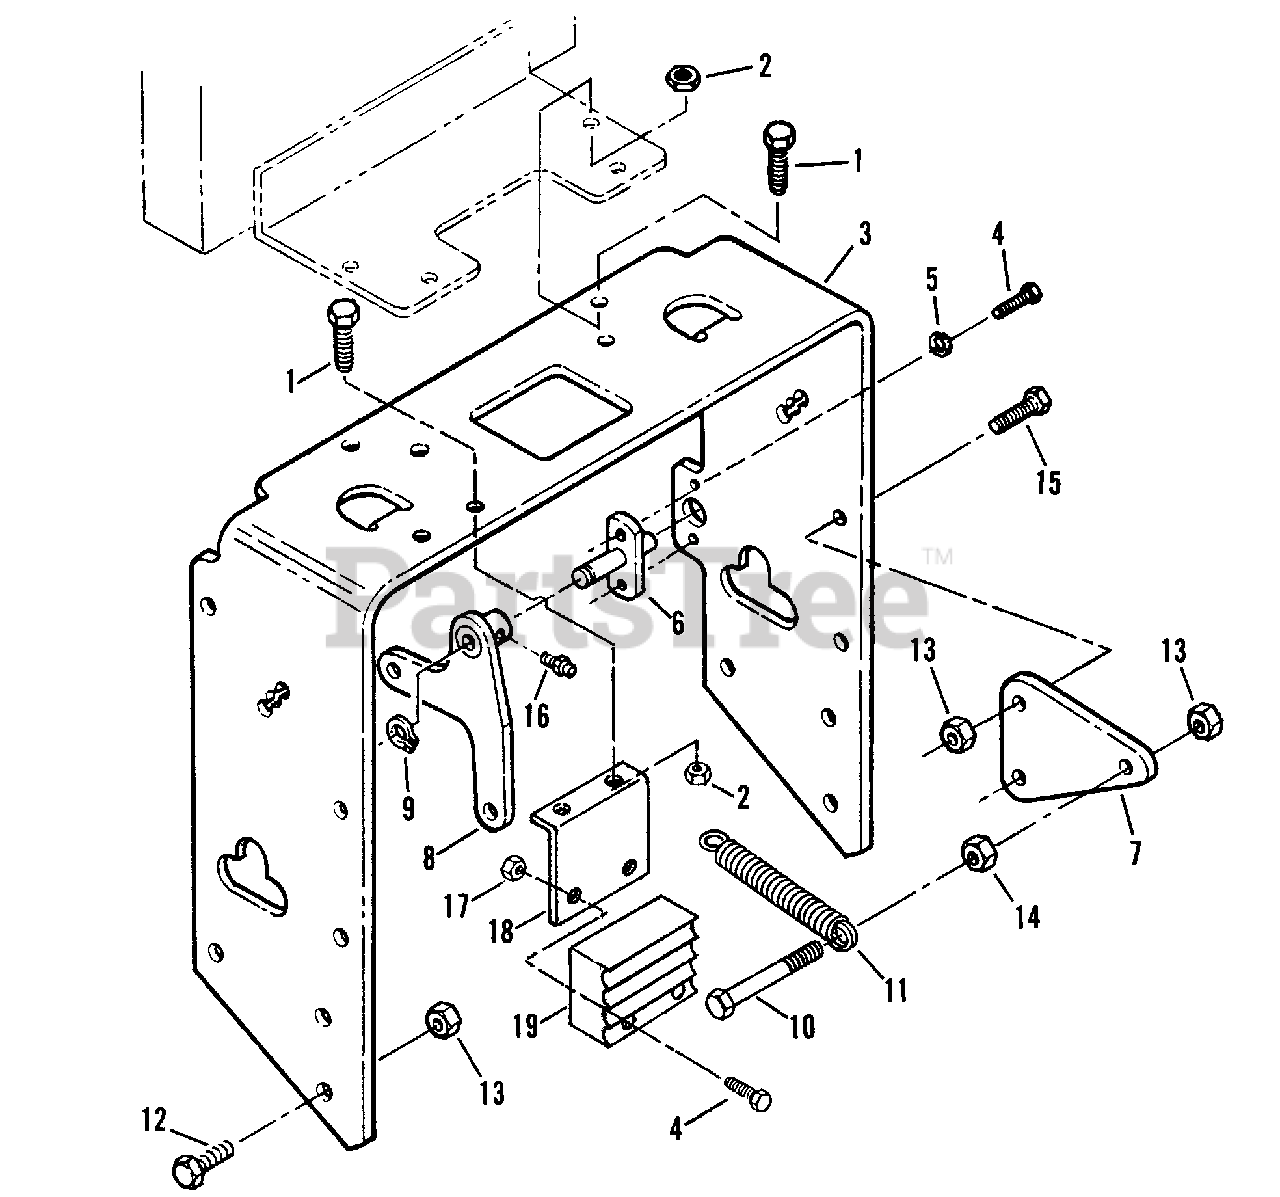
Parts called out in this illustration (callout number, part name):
1	SCREW, 5/16-18 x 1"
2	NUT, 5/16 Nyloc
3	TANK MOUNT BRACKET
4	SCREW, 1/4-20 x 3/4"
5	WASHER, 1/4" Lock
6	BELLCRANK MOUNT
7	SPRING MOUNT PLATE
8	BELLCRANK BLADE WELDMENT
9	RING, 5/8" External Retaining
10	BOLT, 3/8-16 x 2" Hex Head Cap
11	SPRING, Drive
12	BOLT, 3/8-16 x 1" Flanged
13	NUT, 3/8-16 Nyloc
14	NUT, 3/8-16
15	BOLT, 3/8-16 x 1"
16	ZERK, 1/4-28
17	NUT, 1/4-20 Nyloc
18	BRACKET, Module, Electric Clutch
19	MODULE, Electric Clutch
